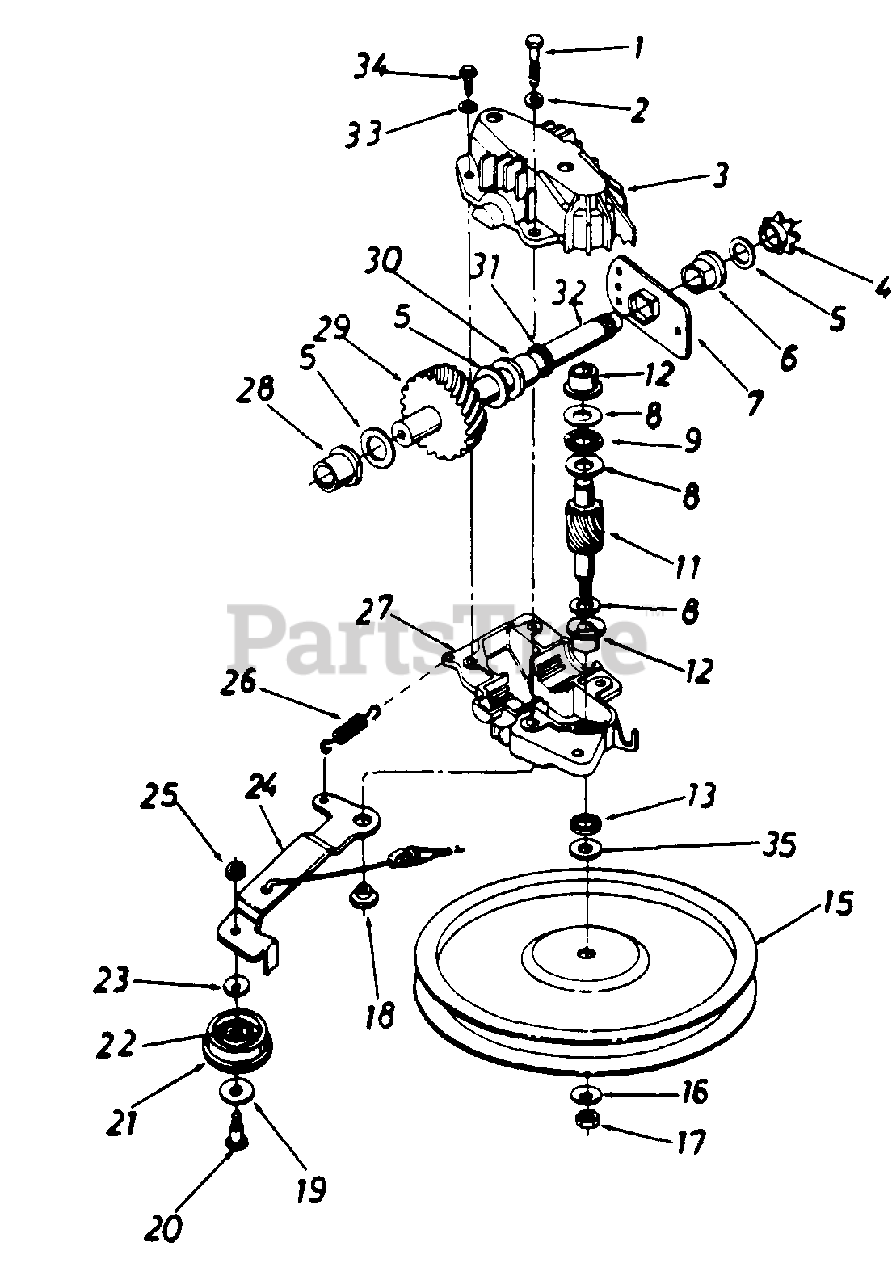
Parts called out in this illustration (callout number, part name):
1	Hex Bolt 1/4-20 x 1.25" Lg. w/Patch
2	L-Wash. 1/4" I.D.
3	Upper Hsg. Half
4	#48 Sprocket 7 Tooth x 1/2 Pitch
5	Fl-Wash. 5/8" I.D. x .030
6	Hex Flange Brg..631" I.D.
8	Thrust Wash..382" I.D. x .70" O.D.
9	Thrust Bearing .375" I.D. x .812" O.D.
11	11 Tooth Pinion Shaft
12	Flange Bearing
13	Oil Seal
15	Fl-Pulley 5.06" O.D.
16	Bell-Wash..265" I.D. x .75"
17	Hex L-Nut 1/4-28 L.H. Thd.
18	Shld. Spacer .375" Dia. x .170
19	Fl-Wash..390" I.O. x 1.0"
20	Shld. Bolt .375" Dia. x .40"
21	Fl-Idler Plastic 1.50" Dia.
22	Needle Brg..375" x .31
23	Bell-Wash..265" I.D. x .75"
24	Idler Brk't. Ass'y.
25	Hex Patch L-Nut 1/4-28 Thd.
26	Extension Spring 1.12" Lg.
27	Lower Hsg. Half
28	Flange Bearing .566 Dia.
29	33 Tooth Helical Gear
30	Flange Bearing .629 Dia.
31	Oil Seal .625 Dia.
32	Gear Sprocket Shaft
33	L-Wash. #10 I.D.
34	Hex B-Tap Scr. #10 x .62"
35	Hex Washer .26" x .88"
